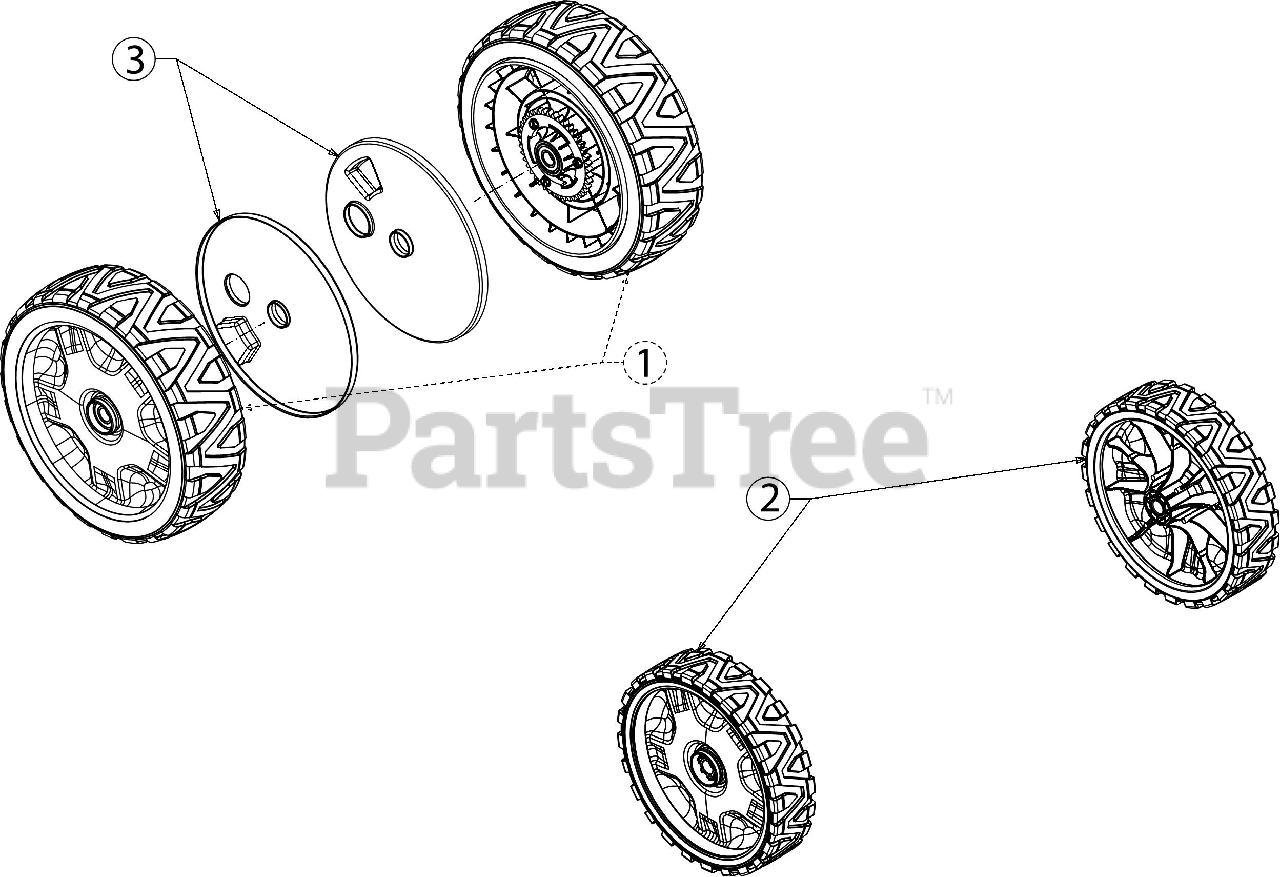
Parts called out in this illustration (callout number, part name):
1	DRIVE WHEEL ASSEMBLY 10 x 3 CRAFTSMAN
1	BALL BEARING
1	HEX SCREW HEAD #10-16 x 1.25
2	WHEEL ASM-8X2 (BLACK)
3	DUST COVER 10"
